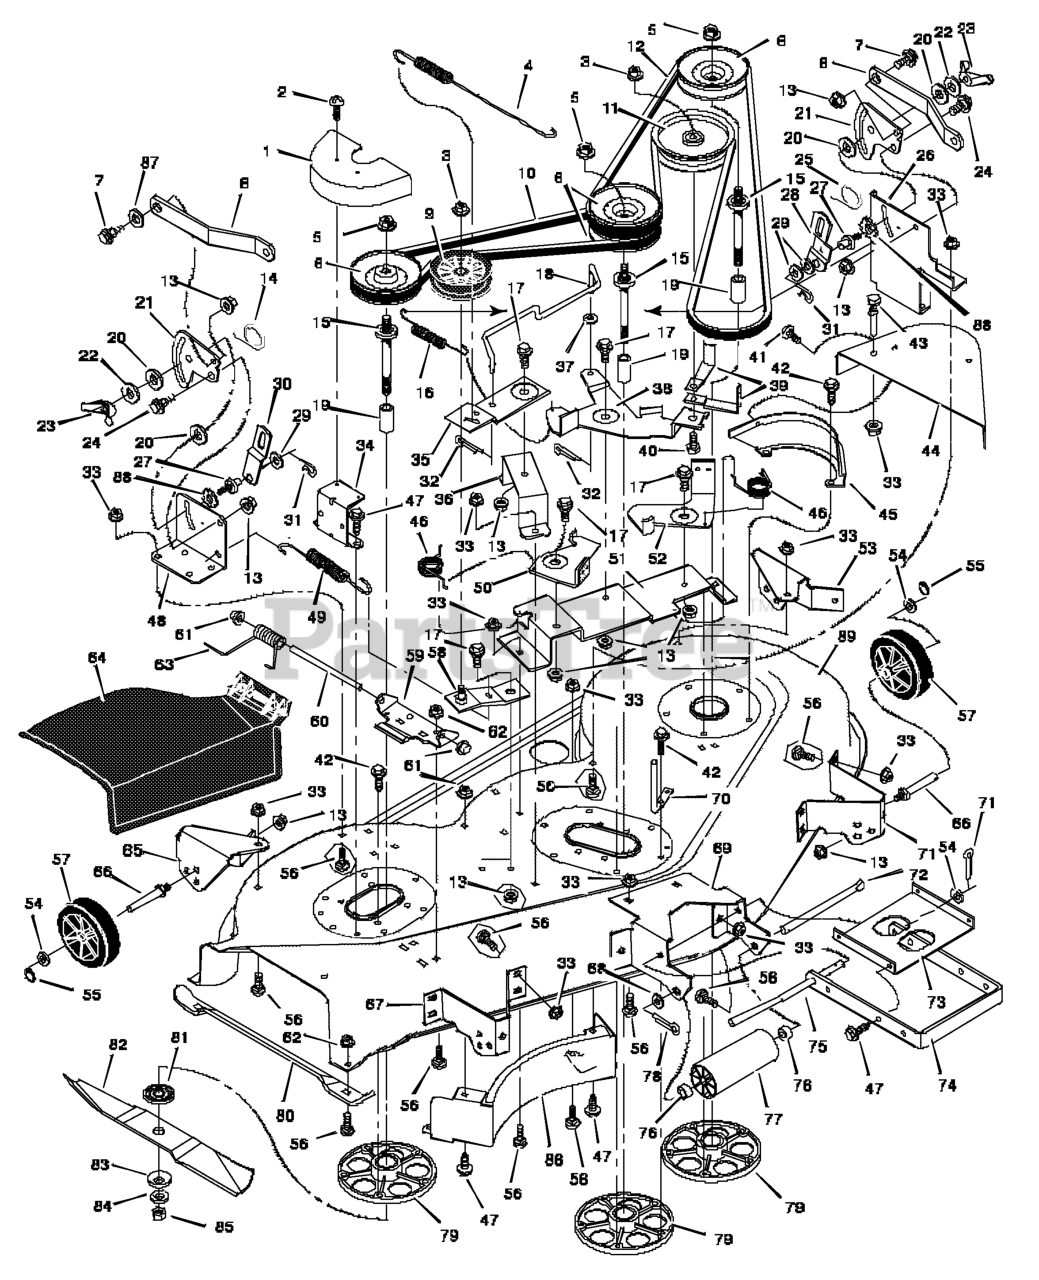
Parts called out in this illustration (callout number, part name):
1	Cover, Right Pulley
2	Screw
3	Nut, Flange
4	Spring, Extension
5	Nut, Flange
6	Pulley
7	Bolt, Shoulder
8	Bracket, Rear Suspension
9	Pulley, Idler
10	Belt, Secondary
11	Pulley, Idler
12	Belt, Primary
13	Nut, Hex
14	Spring, Torsion
15	Shaft, Splined
17	Bolt, Shoulder
18	Link, Bell Crank
20	Pad, Friction
21	Plate, Suspension
24	Bolt, Shoulder
25	Spring, Torsion
26	Bracket, Left Lift
27	Pin, Hanger
28	Link, Left Lift
30	Link, Lift
31	Pin, Hair
32	Pin, Cotter
33	Nut, Flange
34	Bracket, Cover
35	Crank, Bell
36	Bracket, Bell Crank
38	Idler, Arm
39	Guide, Belt
40	Bolt, Idler Pulley
42	Screw
43	Guide, Belt
44	Cover, Left Pulley
45	Bracket, Pulley Cover
48	Bracket, Right Lift
49	Spring, Extension
50	Brake Assembly, Right
51	Plate, Brake Arm
52	Brake Assembly, Left
53	Bracket, Left Rear Gauge Wheel
55	Ring, Locking
56	Bolt, Carriage
57	Wheel, Gauge
58	Arm, Idler
59	Bracket, Hinge
60	Rod, Deflector
61	Push On Cap
62	Nut, Flange
63	Spring, Torsion
64	Deflector, Chute
65	Bracket, Right Rear Gauge Wheel
66	BOLT, Gauge Wheel
67	Bracket, Front Gauge Wheel
69	Bracket, Front Deck
70	Guide, Belt
71	Pin, Cotter
72	Rod, Roller
73	Stiffener
74	Bracket, Suspension
75	Rod, Suspension Bracket
78	Pin, Cotter
79	Housing, Jackshaft
80	Guard, Horn
81	Adapter, Blade
83	Washer, Belleville
86	Baffle
87	Washer
89	Housing, Blade
